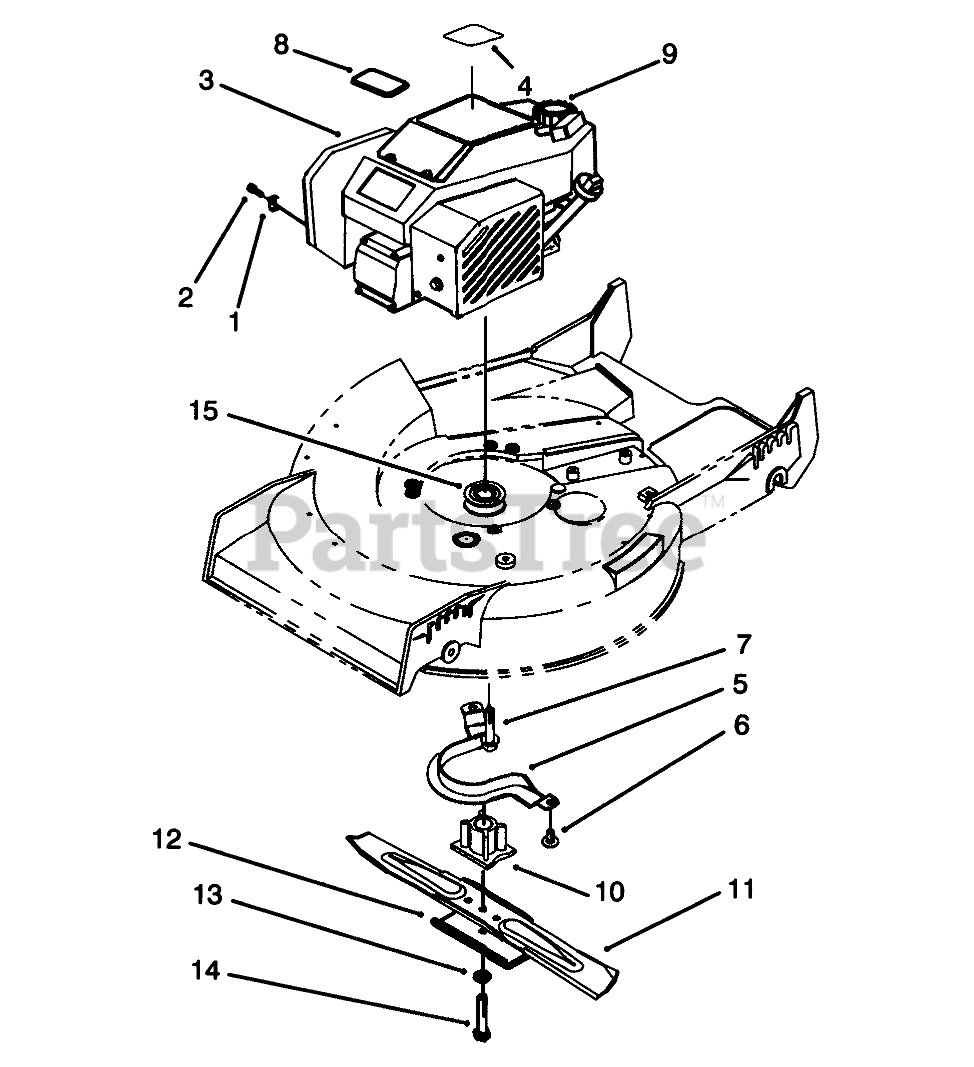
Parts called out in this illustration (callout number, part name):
1	CLAMP-CASING
2	Screw
3	Engine (Incl. Ref. #4, 8, & 9)
4	DECAL - ENGINE
5	Guide-Belt
6	SCREW-HWHTF
7	SCREW-HWH
8	TORO LOGO PLATE
9	GAS CAP ASM
10	BLADE RETAINER
11	Blade
12	Stiffener
13	WASHER-LOCK
14	SCREW-BLADE
15	PULLEY-DRIVE, ZONE START
